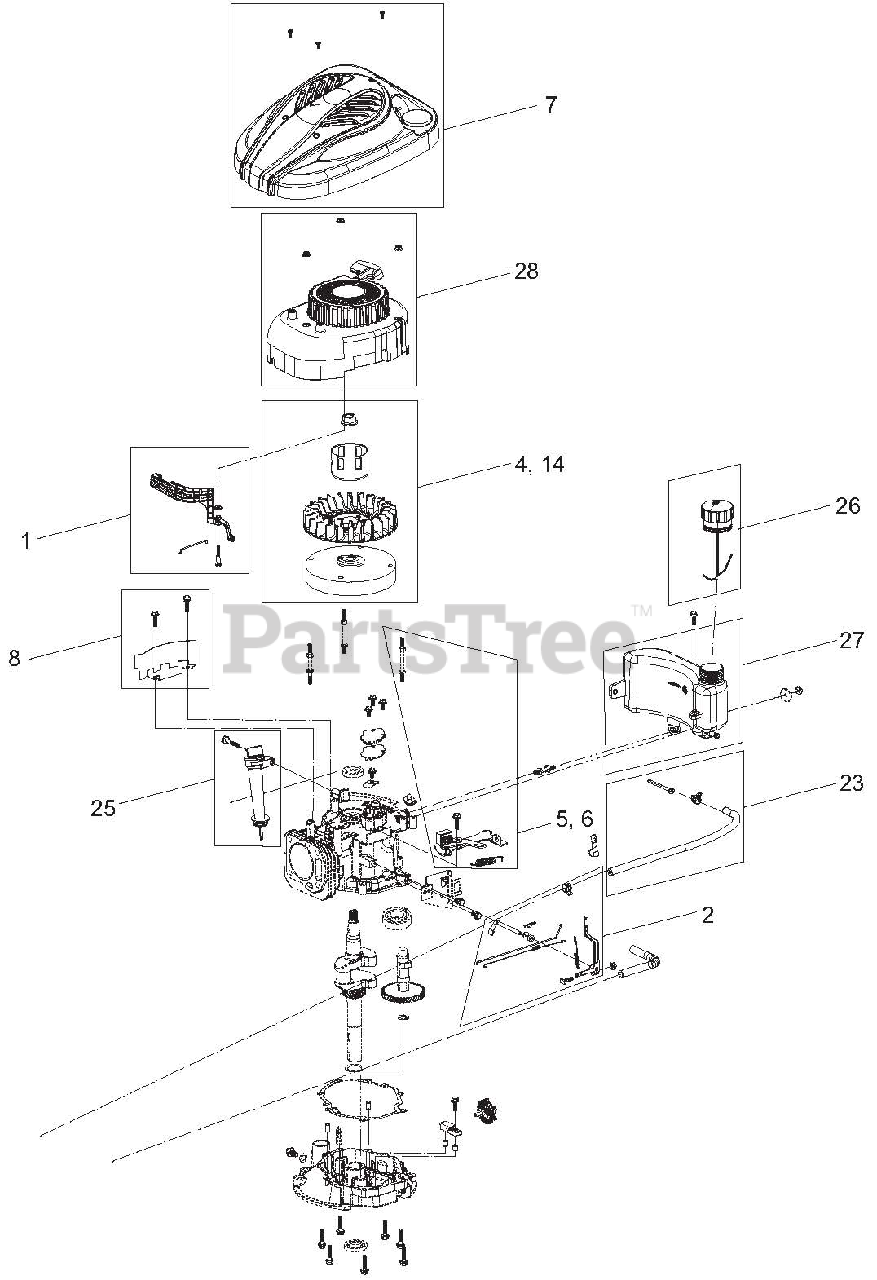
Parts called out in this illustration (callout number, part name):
1	KIT, AIR VANE CHOKE - SVC
2	KIT, GOVERNOR ARM - SVC
4	KIT, FLYWHEEL AND FAN - SVC
5	KIT, BRAKE ASM RECOIL - SVC
6	KIT, E-START BRAKE ASM - SVC
7	KIT, ARIENS STYLE - SVC
8	KIT, FLYWHEEL SHIELD - SVC
14	KIT, FLYWHEEL AND FAN - SVC
23	KIT, FUEL LINE W/FILTER - SVC
25	DIPSTICK, OIL - SVC
26	CAP, FUEL - SVC
27	ASM, FUEL TANK W/HARDWARE
28	KIT, RECOIL - SVC
